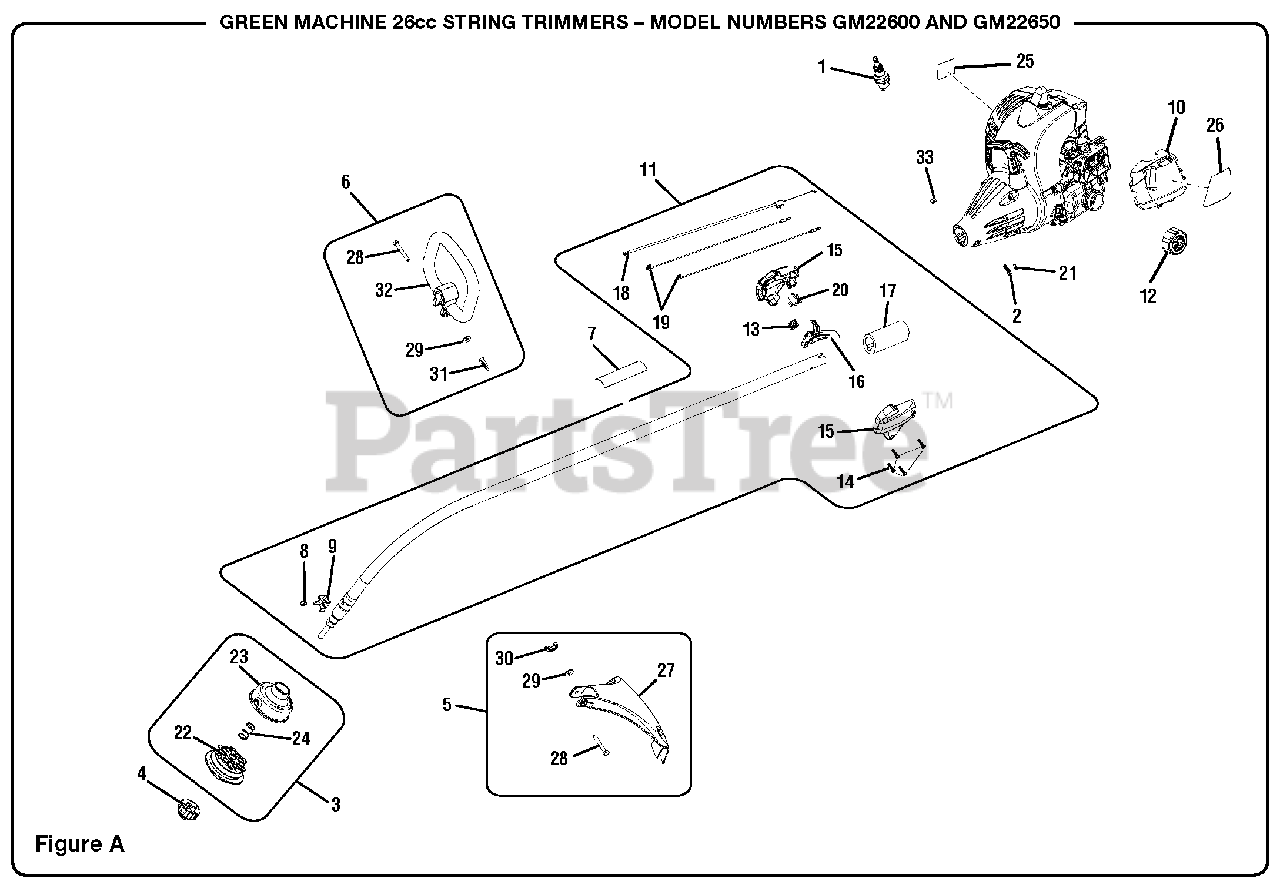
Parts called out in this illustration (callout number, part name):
1	Spark Plug (Champion RCJ6Y)
2	Screw (M6 x 20 mm)
3	String Head Assembly
4	Spool Retainer
5	Grass Deflector Assembly
6	Front Handle Assembly
7	Icon Strip
8	Screw (10-32 x 3/8 in)
10	Air Box Cover
11	Boom Assembly
14	Screw (M4 x 20 mm)
15	Handle Assembly
16	Throttle Trigger
17	Foam Grip
18	Throttle Cable
19	Electrical Lead
20	Switch
21	Screw (8-16 x 5/16 in)
22	Spool
23	String Head Housing
24	Spring
25	Combustion Warning Label
26	Starting Label
27	Grass Deflector
28	Bolt (1/4-20 x 2 in)
30	Wing Nut (1/4-20)
31	Wing Nut (1/4-20)
32	Front Handle
33	Hex Nut (M6)
